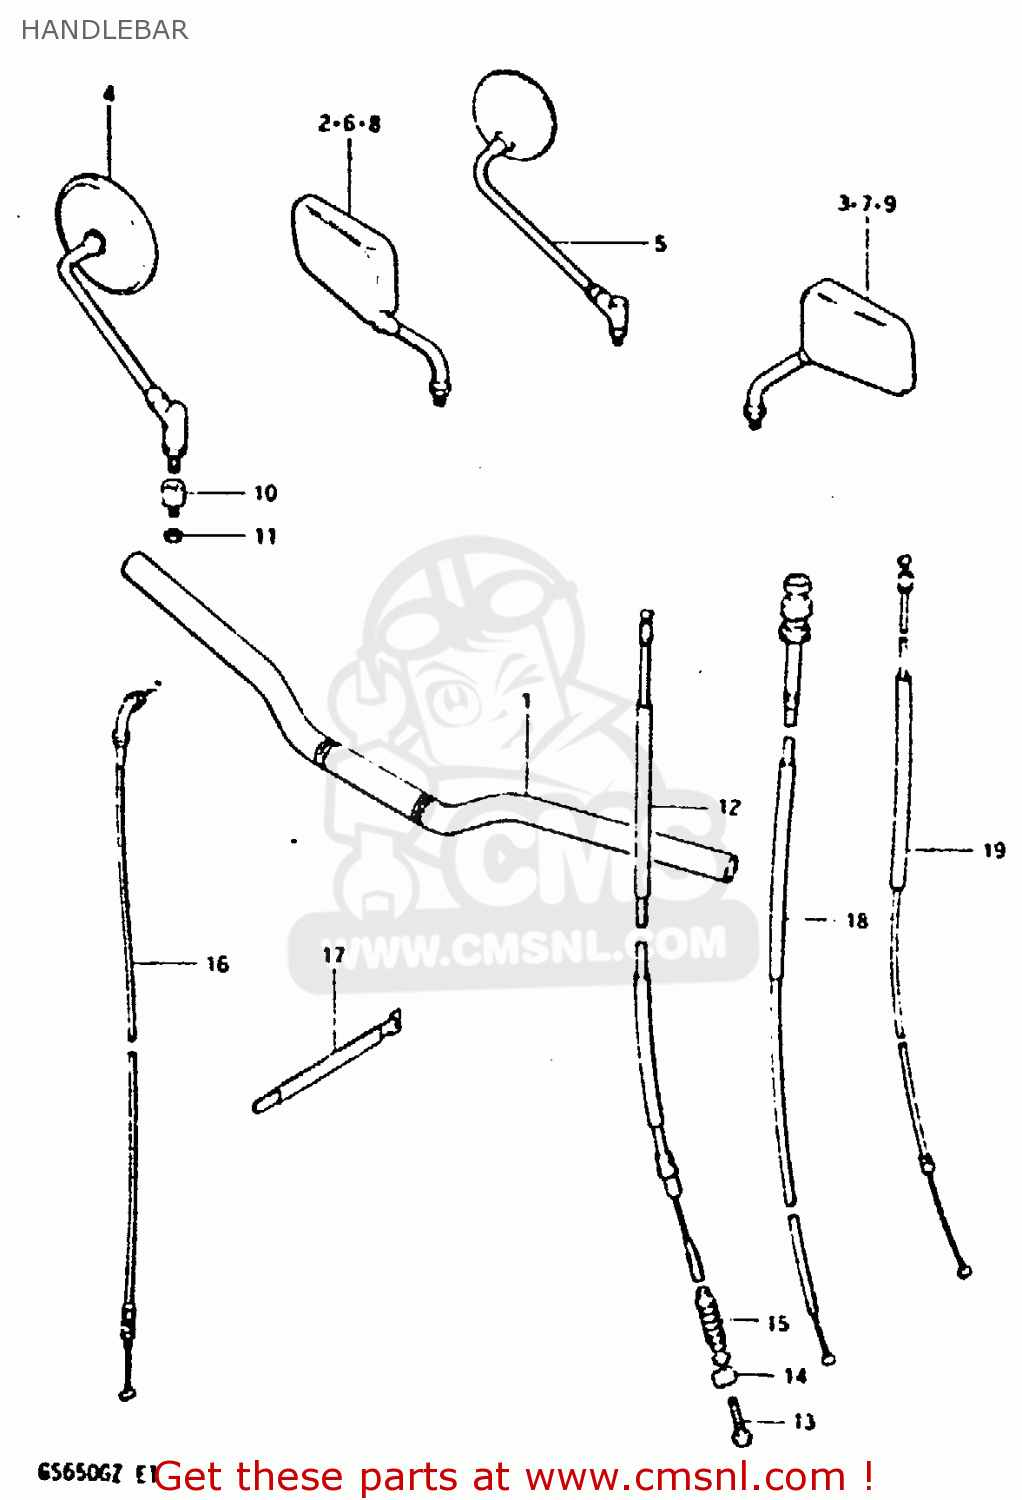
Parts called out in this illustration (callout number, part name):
1	HANDLEBAR (FLAT)
4	MIRROR ASSY,RH
10	CUSHION,REAR VIEW MIRROR
11	NUT
12	CABLE, CLUTCH (FLAT)
13	SCREW
14	PIN
15	DUST SEAL
16	CABLE ASSEMBLY,THROTTLE
17	CLAMP
18	CABLE, STARTER
19	CABLE, STARTER
